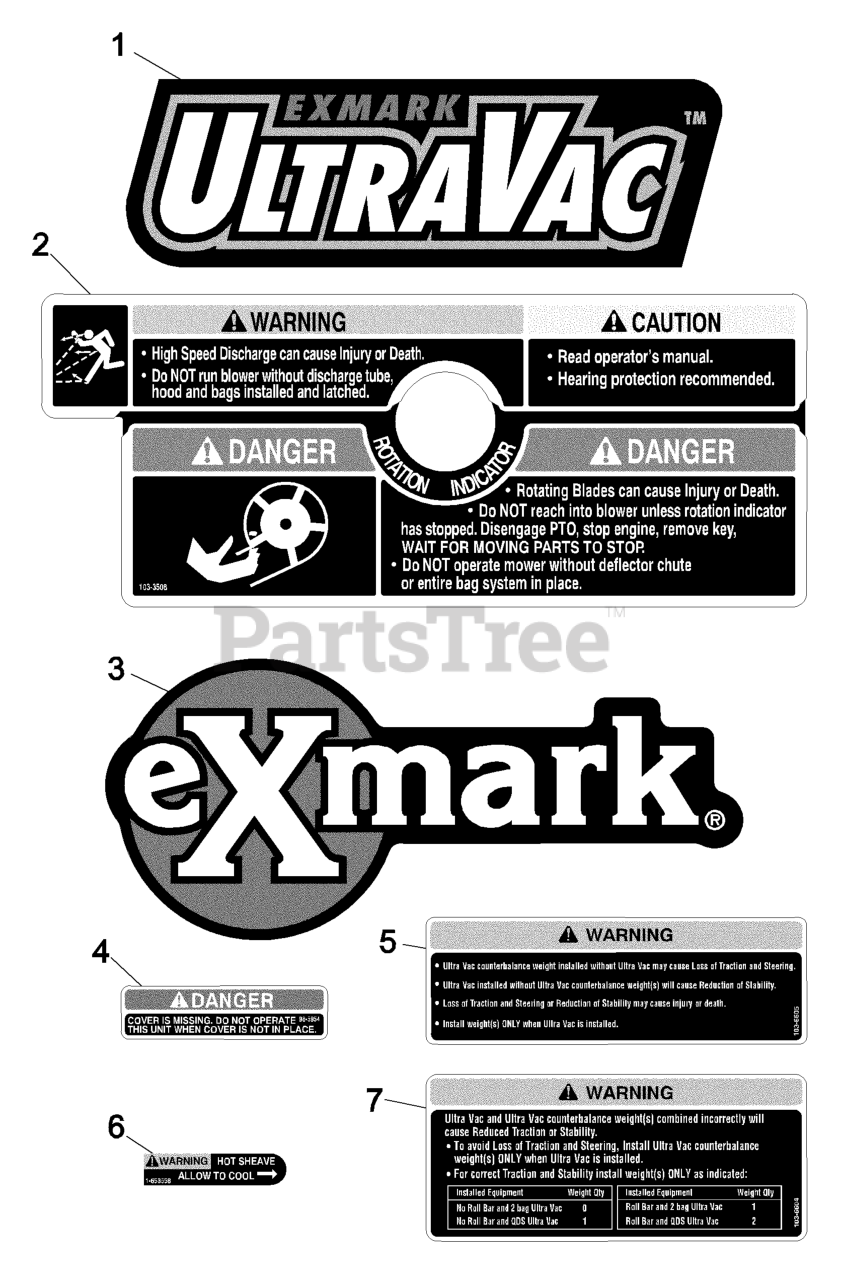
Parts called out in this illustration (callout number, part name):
1	DECAL, ULTRAVAC
2	DECAL-WARNING
3	DECAL, EXMARK LOGO
4	DECAL-COVER, MISSING
5	DECAL,WEIGHT
6	DECAL-WARNING
7	DECAL,WEIGHT
